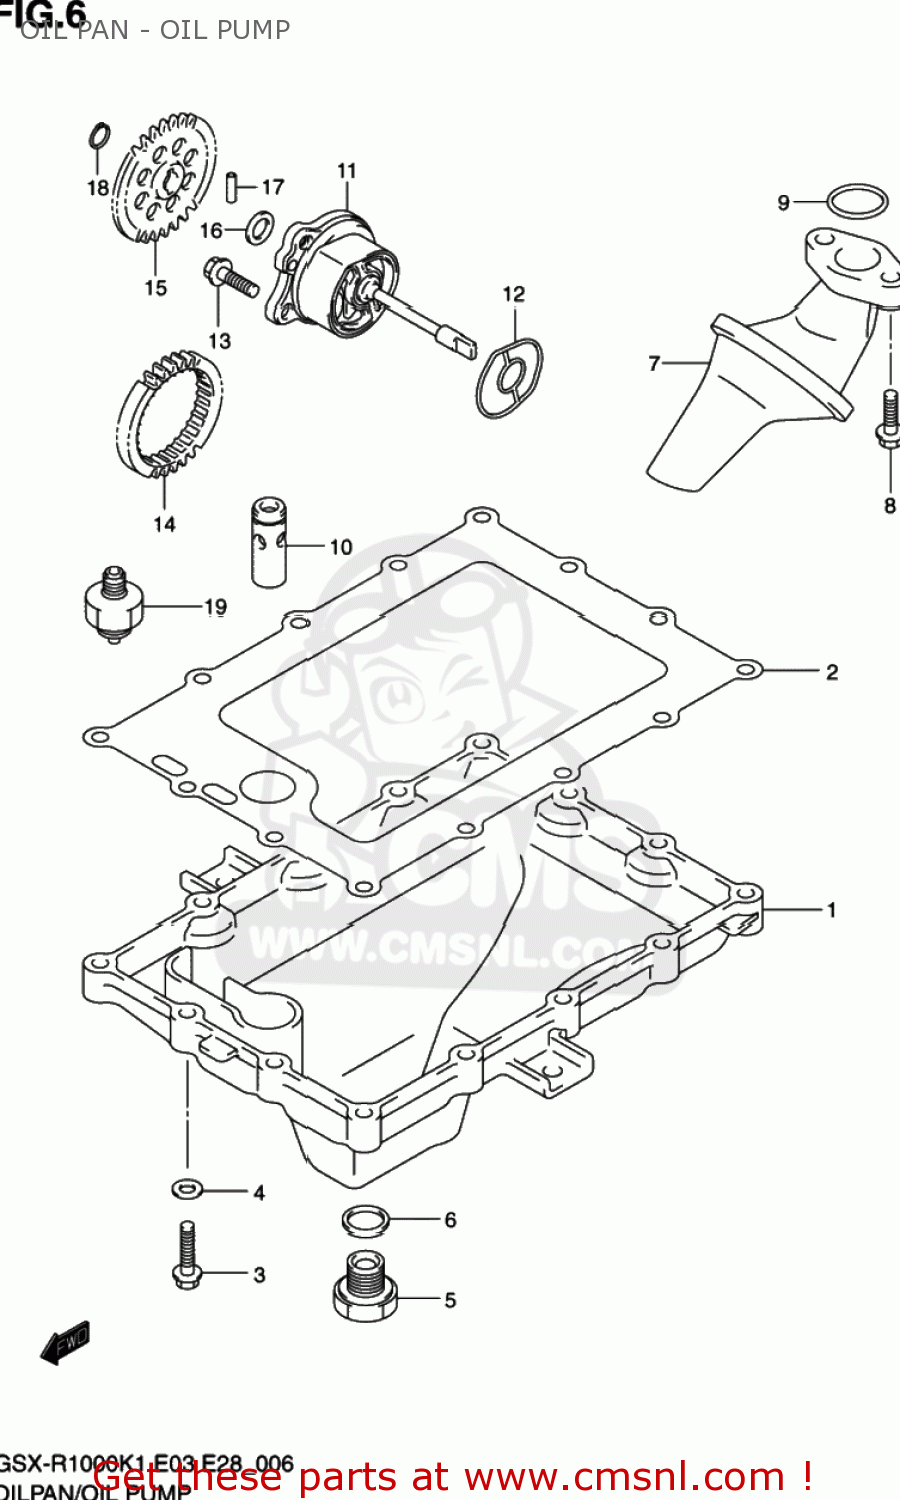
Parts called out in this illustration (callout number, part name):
1	PAN,OIL
2	GASKET,OIL PAN (NAS)
3	BOLT(6X25)
4	GASKET(5.8X13X1.2) (NAS)
5	PLUG(14X20)
6	GASKET(13.8X18.8X4.8) (NAS)
7	STRAINER ASSY,ENGINE OIL
8	BOLT
9	O RING(D:2.62,ID:20.3)
10	VALVE ASSY,OIL RELIEF(7K)
11	PUMP ASSY,ENGINE OIL
12	O RING,OIL PUMP
13	SCREW
14	GEAR,OIL PUMP DRIVE
15	GEAR,OIL PUMP DRIVEN
16	SHIM(10X18X0.5)
17	PIN(4X15.8)
18	CIRCLIP,10MM
19	SWITCH ASSY,OIL PRESSURE
